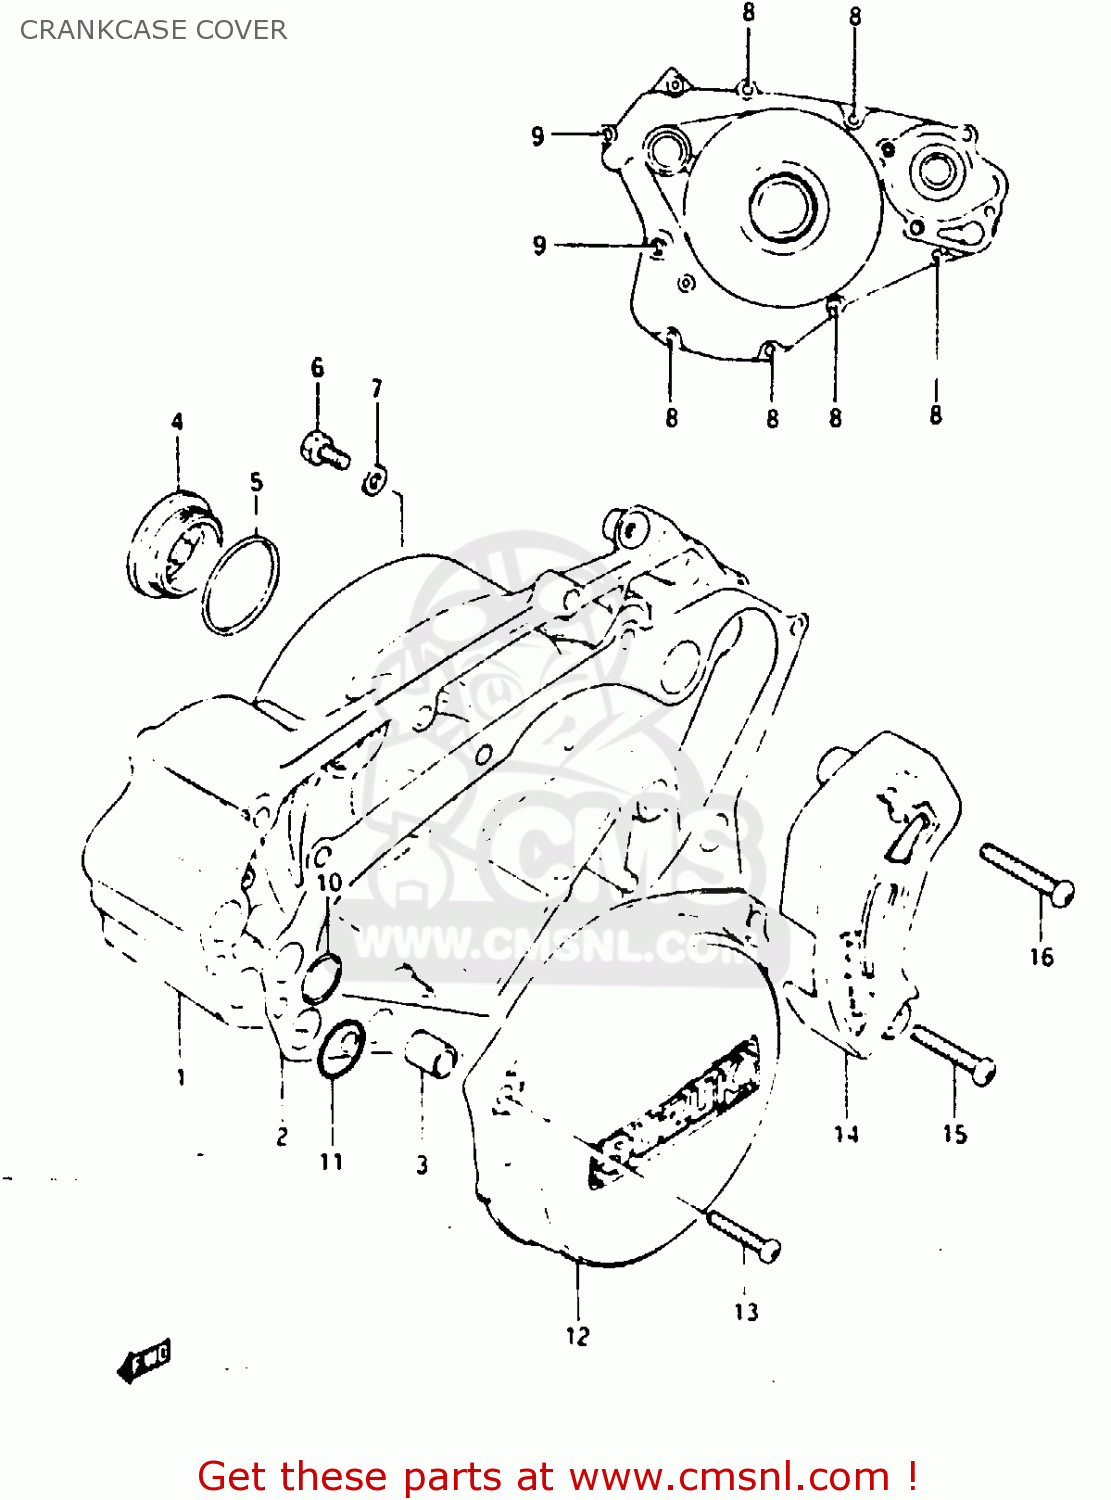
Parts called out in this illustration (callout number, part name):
1	COVER, CLUTCH
2	GASKET, CLUTCH COVER
3	PIN
4	PLUG
5	O RING(D:3.1,ID:32.7)
6	SCREW(6X10)
7	GASKET(6.2X11X1) (NAS)
8	SCREW
9	SCREW
10	O RING(D:1.9,ID:14.5)
11	O RING(D:1.9,ID:19.8)
12	COVER, MAGNETO
13	SCREW
14	COVER, SPROCKET
15	SCREW
16	SCREW
